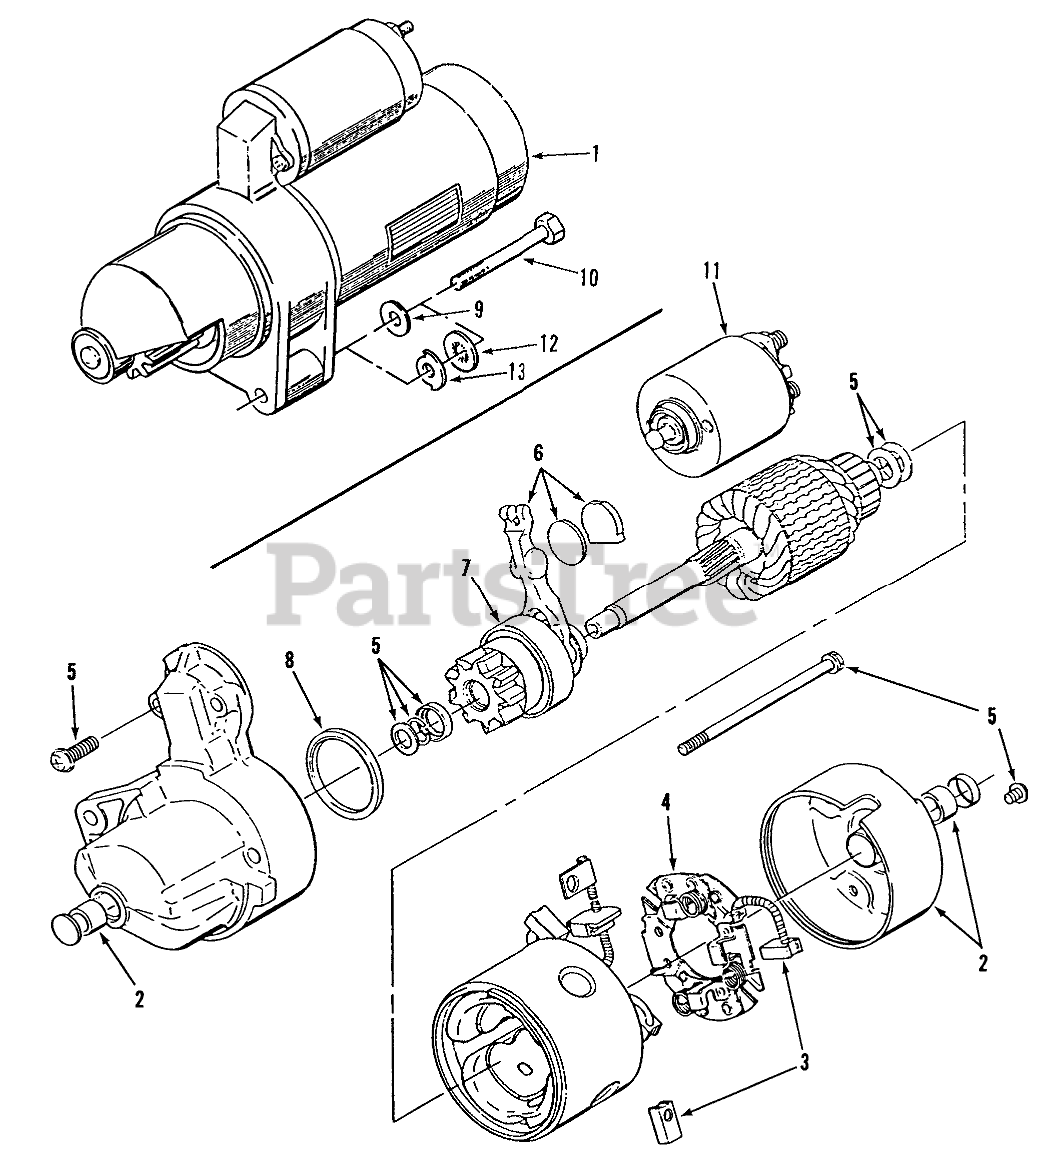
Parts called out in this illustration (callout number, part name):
1	Starter, Complete-See Components Below
2	Bushing Kit (Includes Front Bushing and Rear Cap w/Bushing)
3	Starter Brush Kit (Includes Positive Brush (2) and Negative Brush w/Pigtail)
4	Starter Brush Holder (Includes Brush Holder w/Negative Brush)
5	Starter Hdwr Kit (Includes Solenoid Screws (2), Brush Holder Screws (2), Thru Bolts (2), Armature Shims (2), Pinion Stop Collar, and Pinion Retaining Ring)
6	Starter Shift Lever Kit (Includes Shift Lever, Wear Plate and Rubber Plug)
7	Starter Clutch (Includes Pinion Gear w/Clutch)
8	Dust Seal
9	Washer
10	Bolt
11	Starter Solenoid Kit (Includes Solenoid, Spring and Plunger)
12	WASHER
13	WASHER
